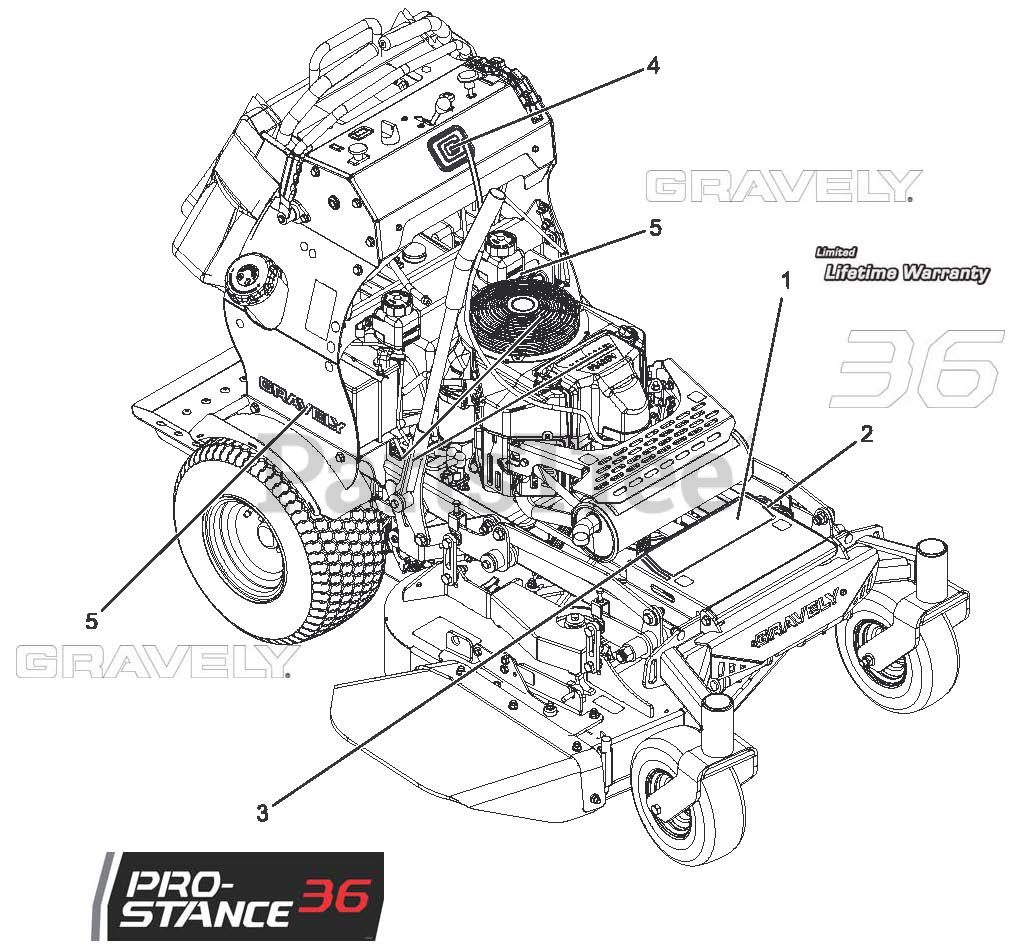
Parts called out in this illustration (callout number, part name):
1	DECAL, LIMITED LIFETIME WARR
2	DECAL, 36"
3	DECAL, PROSTANCE 36
4	DECAL, GRAVELY BRAND
5	DECAL, 9.5" GRAVELY LOGO
